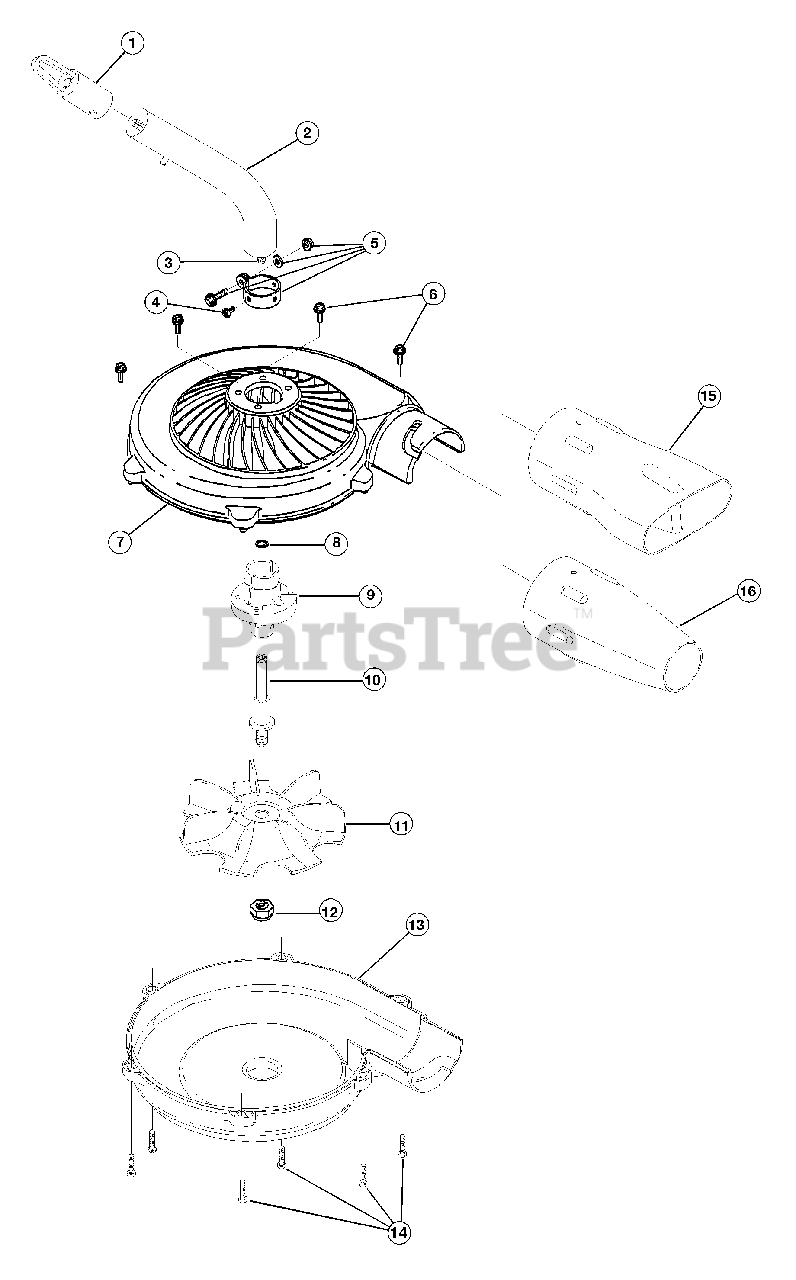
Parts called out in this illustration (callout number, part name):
1	Hanger
2	Drive Shaft Housing Assembly
3	Drive Shaft Assembly
4	Anti-Rotation Screw
5	Lower Clamp Assembly
6	Mounting Screw
7	Upper Housing
8	Palnut
9	Bushing Assembly Housing
10	Shaft Impeller
11	Impeller
12	Lock Nut
13	Lower Housing
14	Mounting Screw
15	Flare Nozzle
16	Concentrator Nozzle
